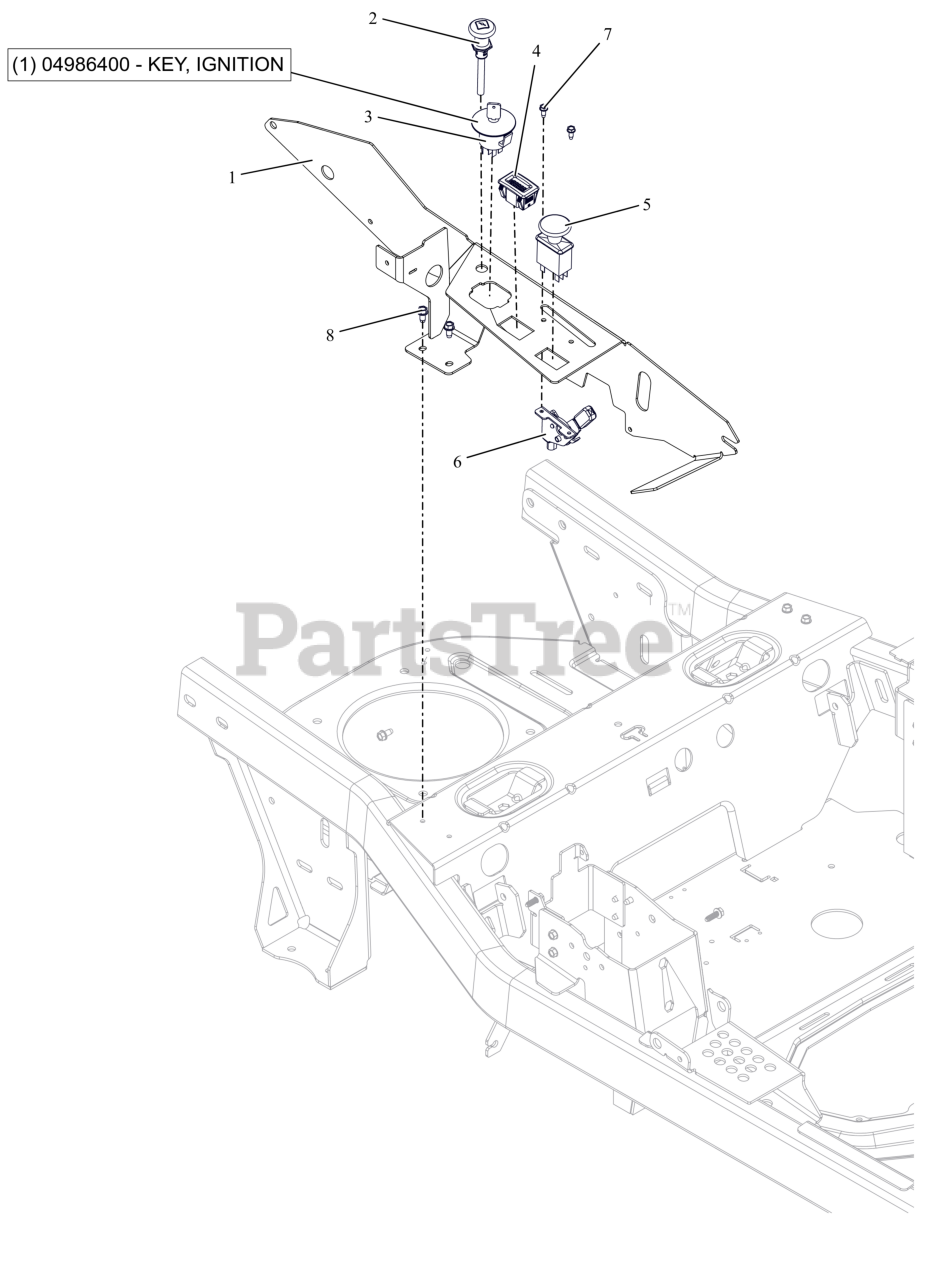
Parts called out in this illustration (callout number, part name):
1	PANEL- CONTROL-RH-GRAVELY
2	CABLE- CHOKE-SNAP IN 37"
3	KEYSWITCH-IGNITION 4 POS
3	KEY, IGNITION
4	HOUR METER
5	SWITCH, CLUTCH
6	CABLE- THROTTLE
7	SCR,TAP #10-24X.50 HWH TR ZCC
8	SCR-TAP .25-20X.50 HWH ZCC
